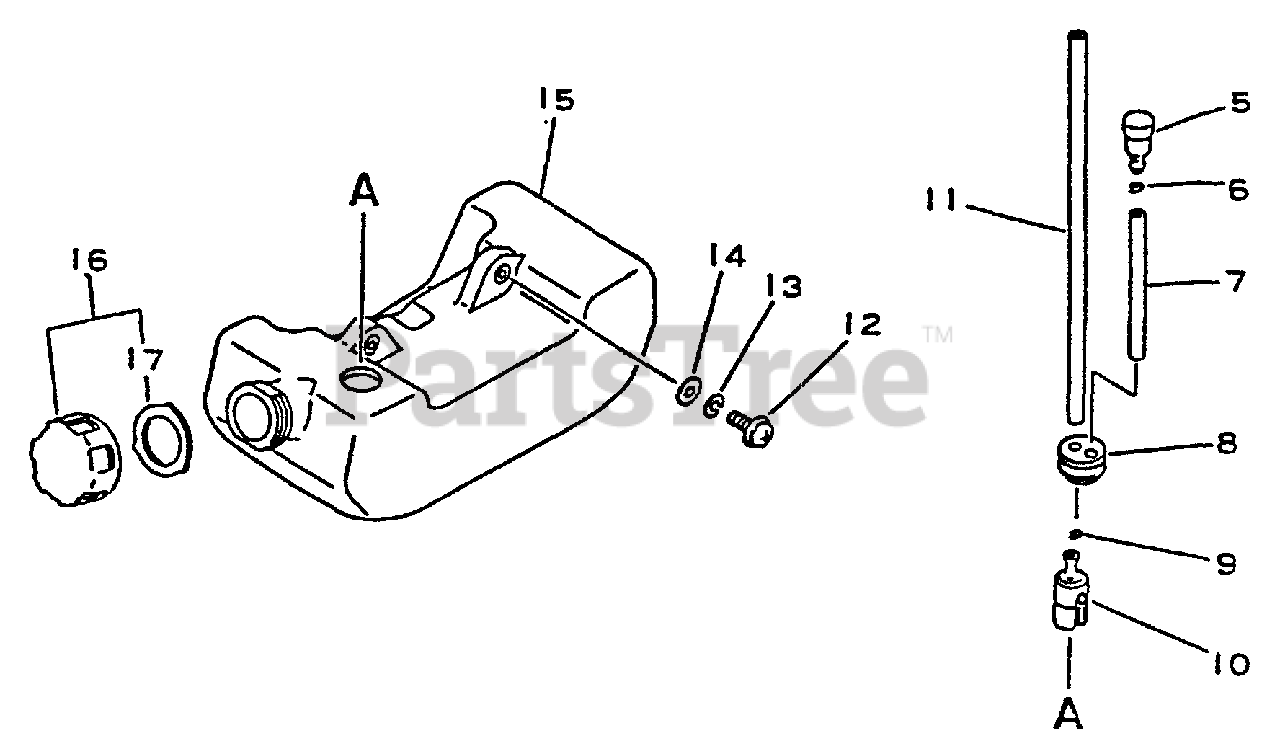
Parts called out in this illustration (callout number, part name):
5	VENT, FUEL TANK
6	RETAINER, PIPE
7	PIPE - 3X5X70 -- BLACK
8	GROMMET
9	CLIP - 6
10	FILTER, FUEL
11	PIPE - 3X5X180 -- BLACK
12	SCREW - 5X10
13	LOCKWASHER - 5
14	WASHER - 5
15	TANK, FUEL
16	CAP ASSY
17	GASKET, CAP
